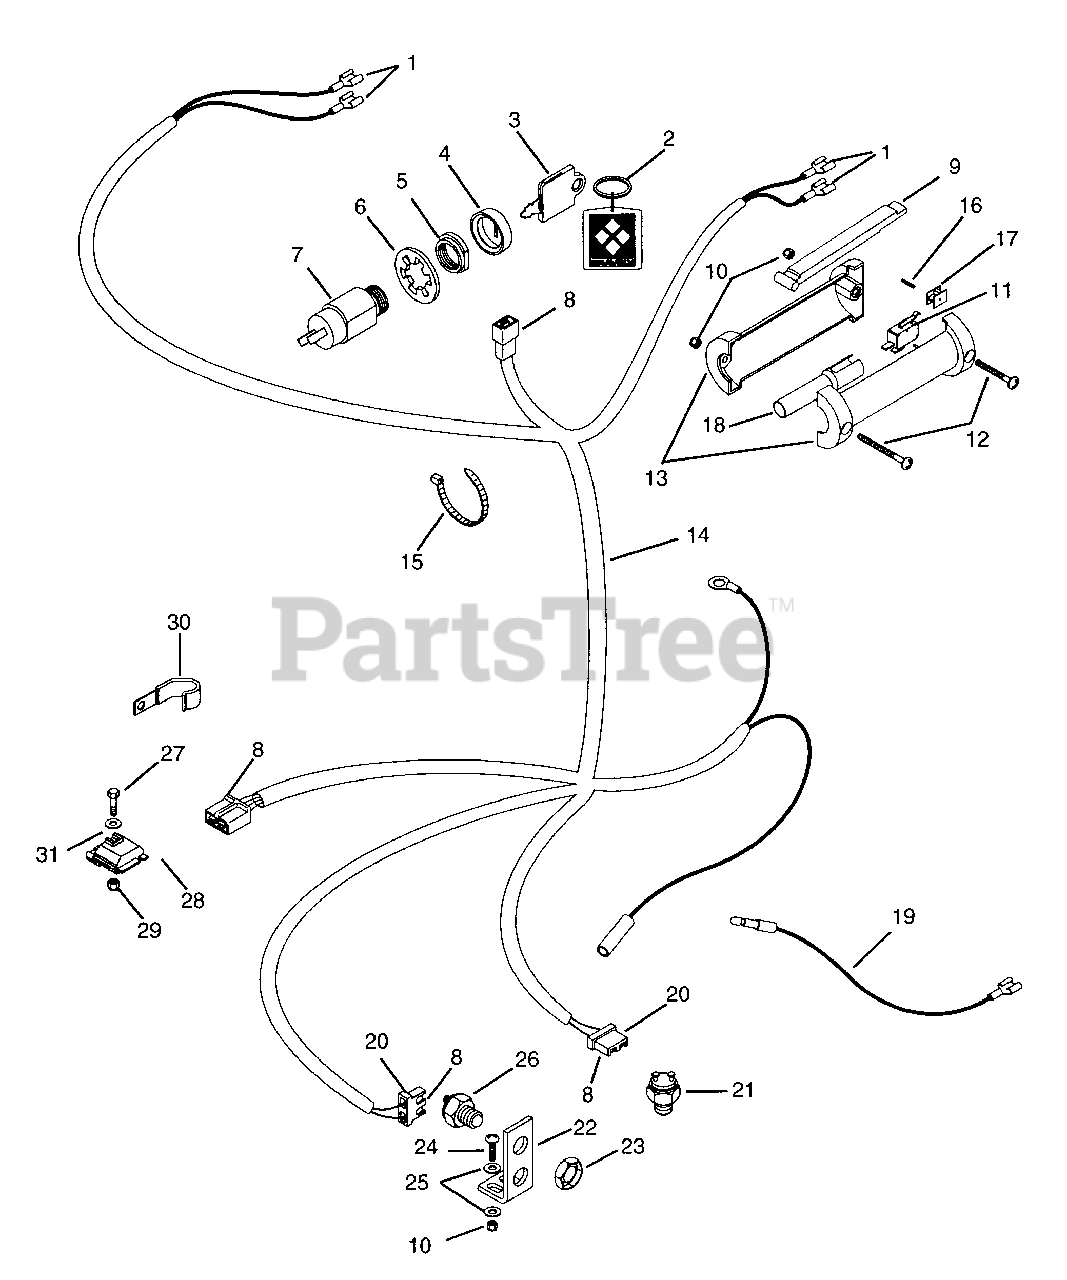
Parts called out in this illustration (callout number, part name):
1	TERMINAL,FEMALE
2	KEY CHAIN
3	KEY -W/CAP
4	CAP - IGNITION SWITCH
5	NUT-PANEL .625-32 GRECO
6	WSHR-LK-INT .625X.045 YWZC
7	SUI,BRAKE&AIR CLNR COMB
8	TERMINAL
10	@NUT-LK-NYL 10-24 W/INSRT YWZC
12	SCR-MCH 10-24X1.50 PH YWZC
13	HANDLE, L.H. & R.H.
14	HARNESS, WIRING
15	TIE WRAP, BLACK LG 7.31
16	PIN-ROLL .094X.750
17	HOLDER, SWITCH
18	INSERT, HANDLEBAR (PROS)
19	WIRE, GROUND
20	CONN,2-WIRE SWITCH
21	SWITCH, NEUTRAL START N.C.
22	BRKT,INTERLOCK SWITCH
23	NUT-STAMPED .56-18
24	@SCR-MCH 10-24X.75 HWH YWZC
25	@WSHR-FL-STL.219X.50X.049 YWZC
26	SWITCH-NEUTRAL START N.O.
27	@BLT-HEX .25-20X.75 GR5 YWZC
28	MODULE, TIME DELAY 1601T
29	@NUT-LK-CTR .25-20 YWZC
31	WSHR-FL-STL.344X.688X.065PL
